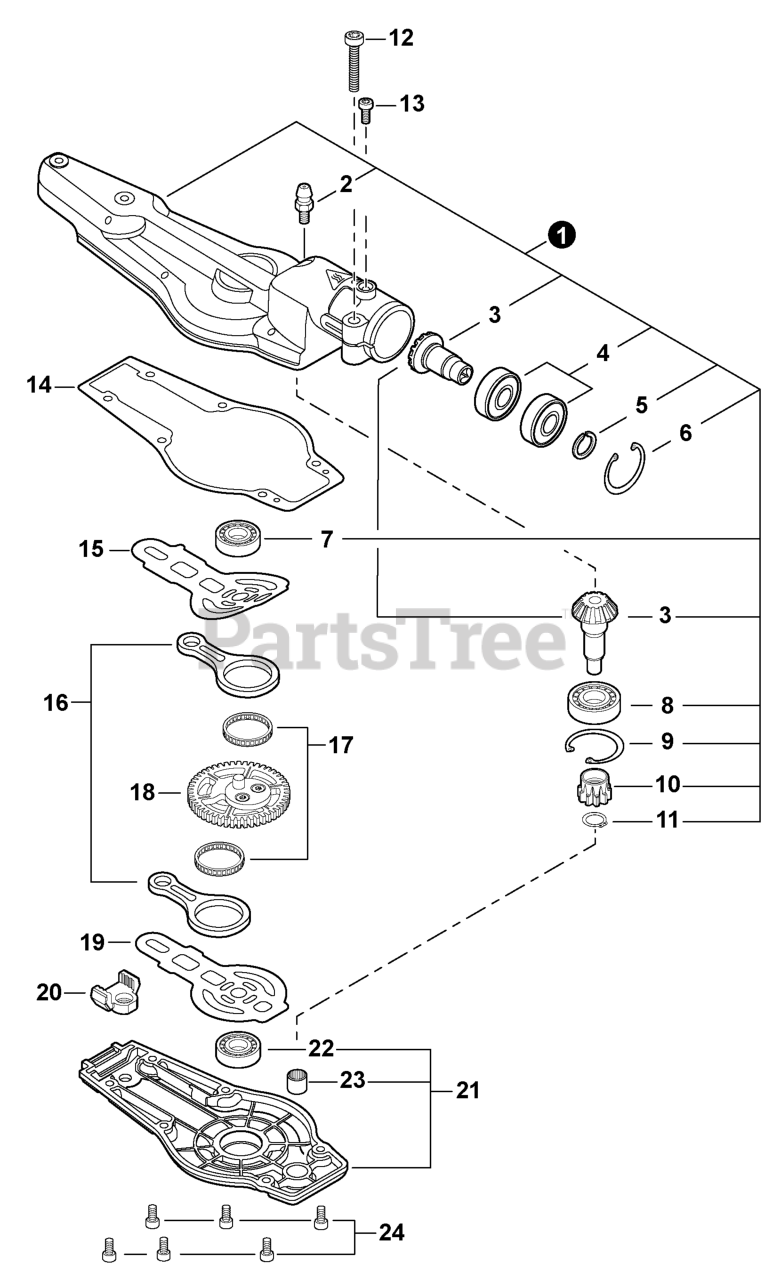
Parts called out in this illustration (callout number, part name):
1	GEAR CASE ASSY
2	FITTING, GREASE
3	GEAR SET, BEVEL
4	BEARING, BALL 6901
5	RING, SNAP 12
6	RING, SNAP 24
7	BEARING, BALL 608
8	BEARING, BALL 6001
9	RING, SNAP 28
10	GEAR, SPUR
11	RING, RETAINING 8
12	BOLT, TORX 5x25
13	BOLT, TORX 5x10
14	GASKET, GEAR CASE
15	PLATE, WEAR
16	ROD, CONNECTING
17	BEARING, NEEDLE 30
18	GEAR, SPUR
19	PLATE, WEAR
21	COVER ASSY, GEAR CASE
22	BEARING, BALL 608
23	BEARING, NEEDLE
24	BOLT, TORX 4x12
